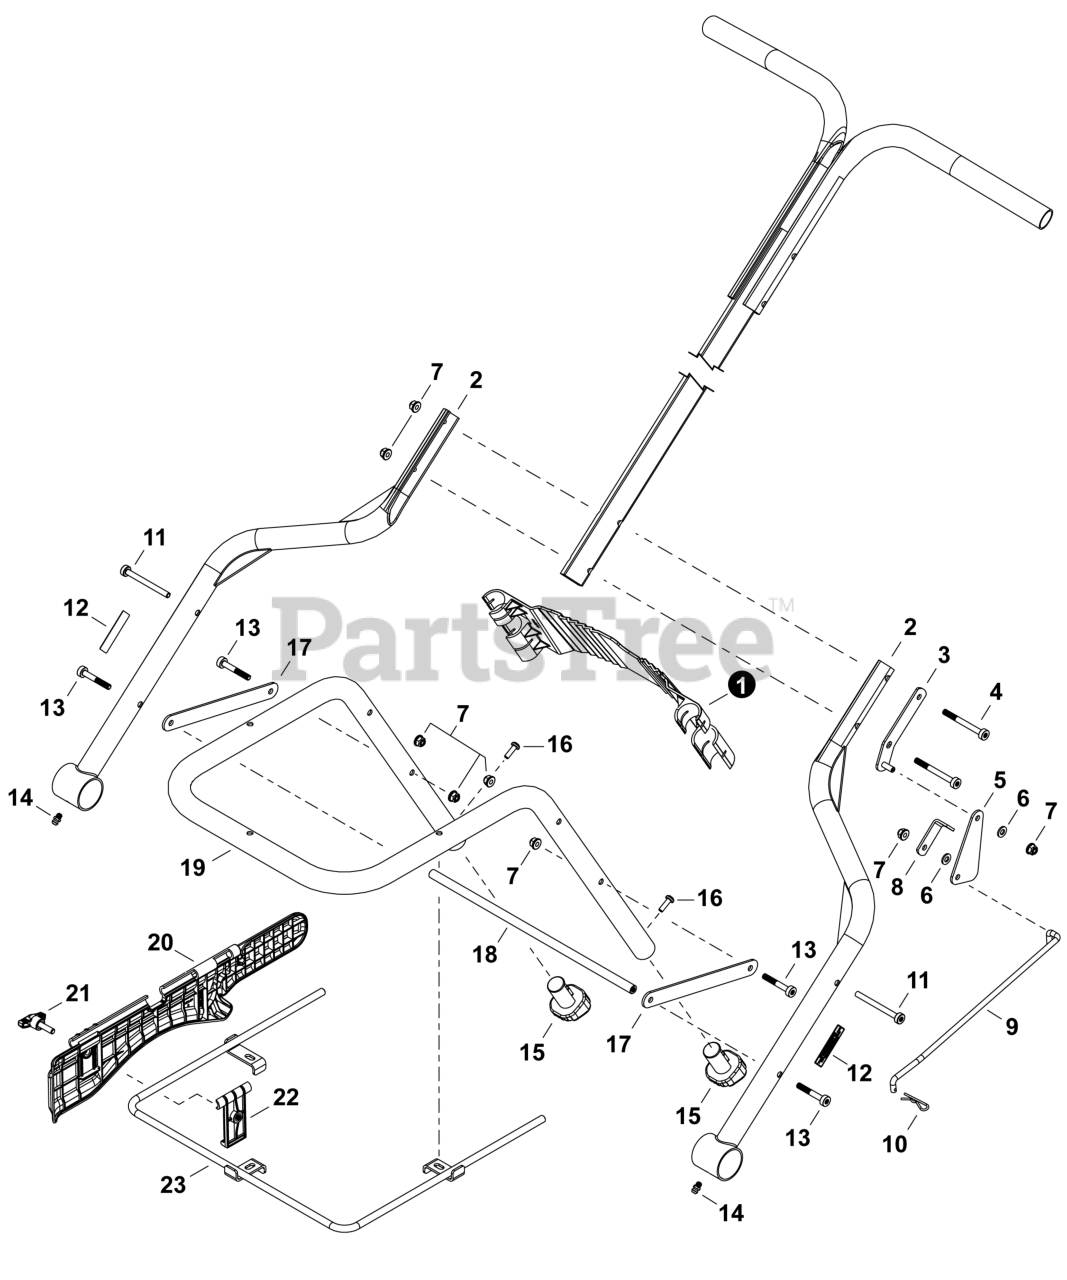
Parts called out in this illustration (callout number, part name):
1	DEFLECTOR - REAR
2	FRAME, AXLE
3	BRACKET, FRAME
4	BOLT, M6 X 60MM
5	PLATE, EYE
7	NUT, FLANGE M6
8	BRACKET, ROD
9	SHAFT, REGULATOR
10	PIN, HITCH
11	BOLT, M6 X 65MM
12	LABEL - CAUTION
13	BOLT 6x40
14	FITTING, GREASE
15	CAP, LEG
16	BOLT, TORX 5x16
17	BRACE, FRAME
18	BRACE, FRAME
19	FRAME, HOPPER
20	DEFLECTOR - RIGHT
21	THUMBSCREW
22	CLAMP, DEFLECTOR
23	BRACKET, DEFLECTOR
